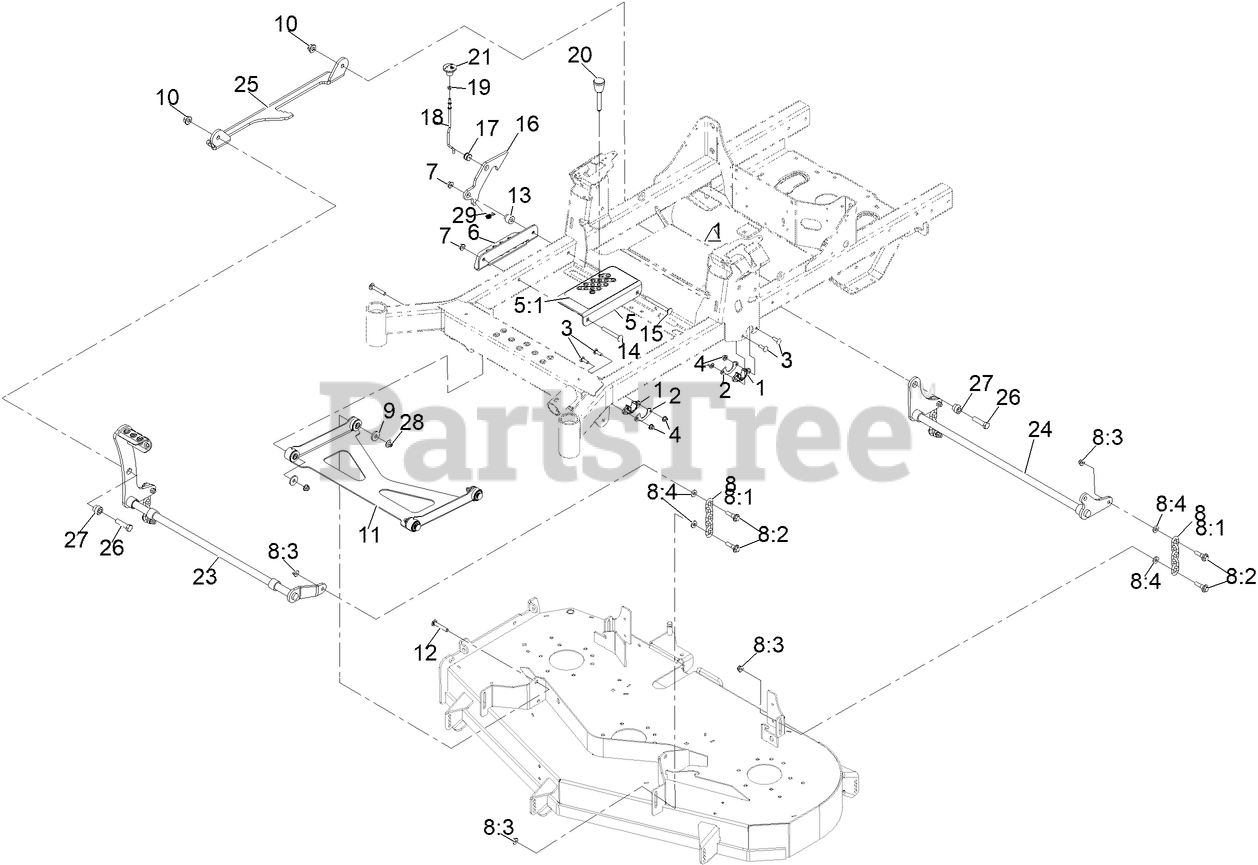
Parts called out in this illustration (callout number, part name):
1	BEARING-FLANGE
2	GUSSET-LIFT, DECK
3	SCREW-CARR
4	NUT-HF, NI
5	BRACKET ASM
5:1	DECAL-HOC
6	Plate, HOC Lower
7	NUT-HF, NI
8	DECK CHAIN ASM
8:1	CHAIN-LIFT, DECK
8:2	BOLT-SHOULDER
8:3	NUT-HF, NI
10	NUT-HF, NI
11	ASM-DECK STRUT WITH BUSHINGS
12	BOLT-CARR, SHORT NECK
13	SPACER-STEPPED
14	SCREW-CARR
15	SCREW-CARR
16	LATCH, TRANSPORT
17	GROMMET
18	LINKAGE, TRANSPORT
19	NUT-JAM
20	PIN-HOC
23	Weld-Decklift Front Shaft
24	Weld-Decklift Rear Shaft
25	LINK-DECKLIFT
26	SCREW-HEX
27	SPACER, HOC
28	Nut-Nyloc 3/8-16 Flg
29	SPRING, EXTENSION
